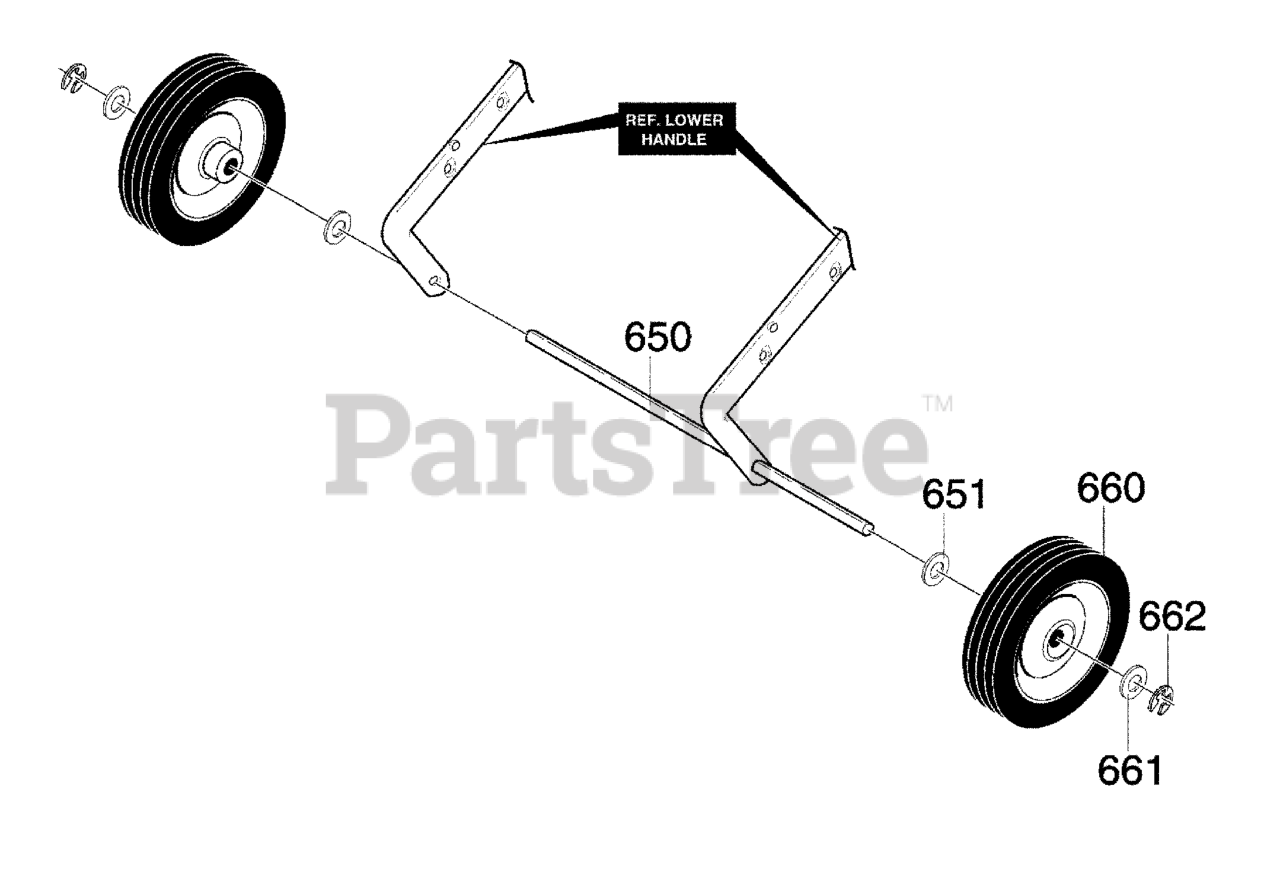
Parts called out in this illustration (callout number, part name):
650	AXLE SHAFT
651	WASHER, FLAT .391X1.00X1.25
660	TIRE & RIM
661	WASHER, FLAT .391X1.00X.125
662	RING, RET E
